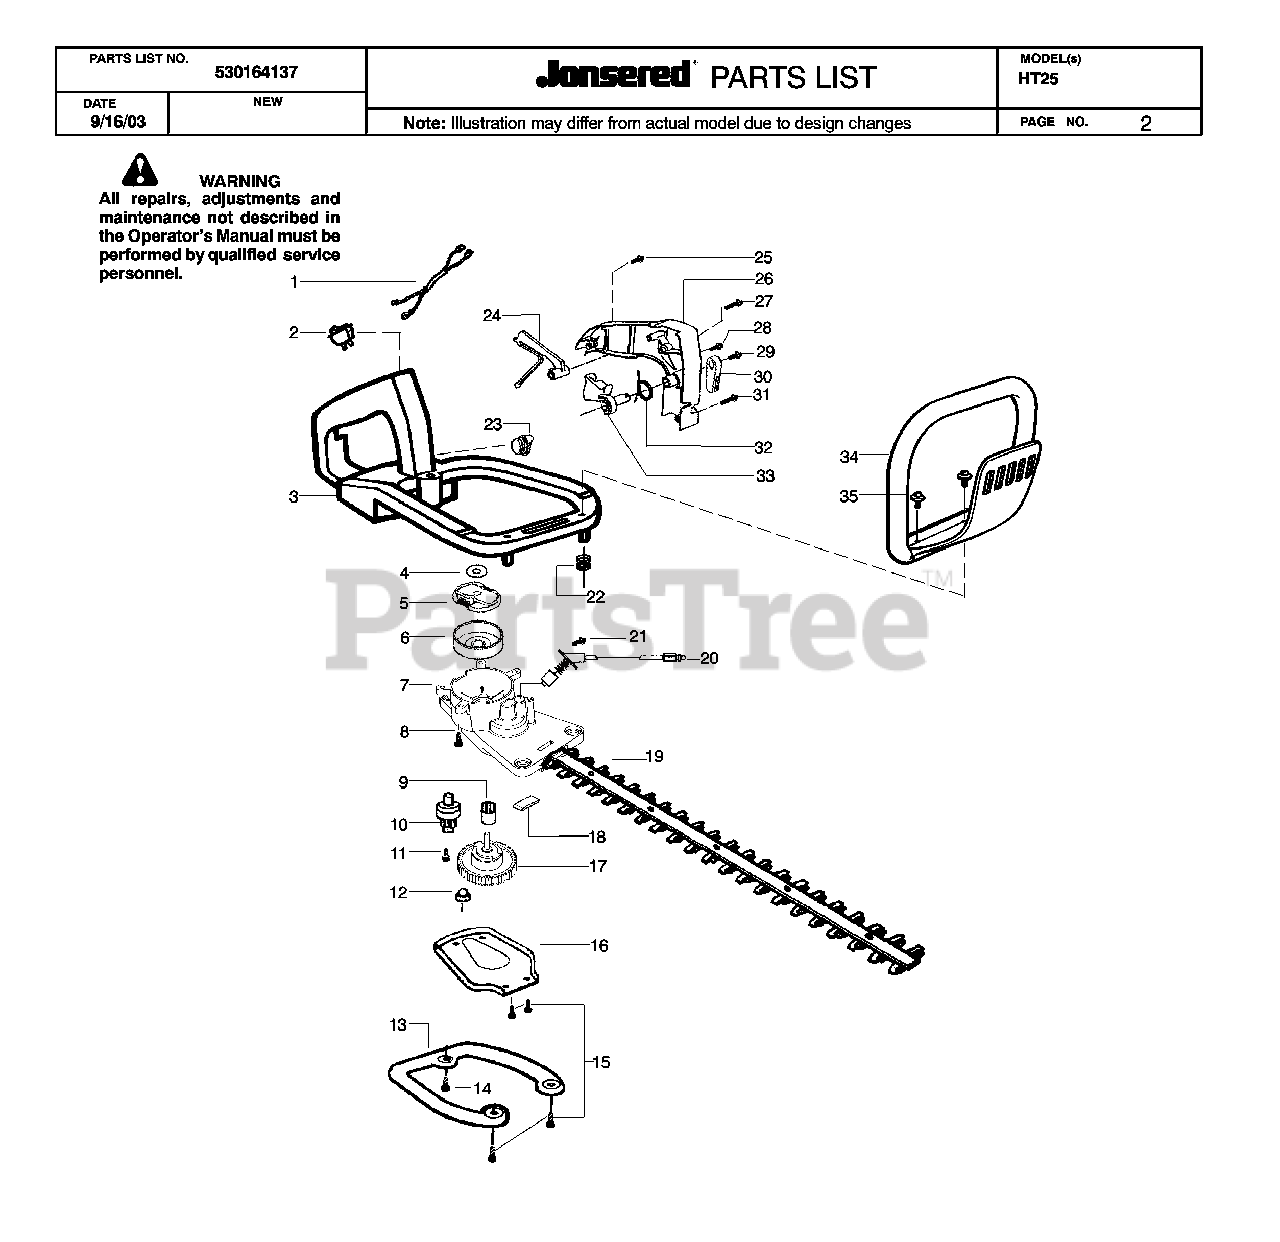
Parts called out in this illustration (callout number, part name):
4	WASHER FLAT
6	CLUTCH DRUM
8	SCREW-10-14 X 13/16 (PL
11	SCREW-10-16 X 1/2, TYPE 2
12	BLADE BUSHING
13	ISOLATOR PLATE
16	PLATE-GEARBOX COVER
19	BLADE ASSEMBLY
22	ANTIVIBE MOUNT
23	FUEL CAP
29	SCREW 8-16 X 9/16 (PLAS
31	SCREW-10-16 X 1-3/8 PLA
